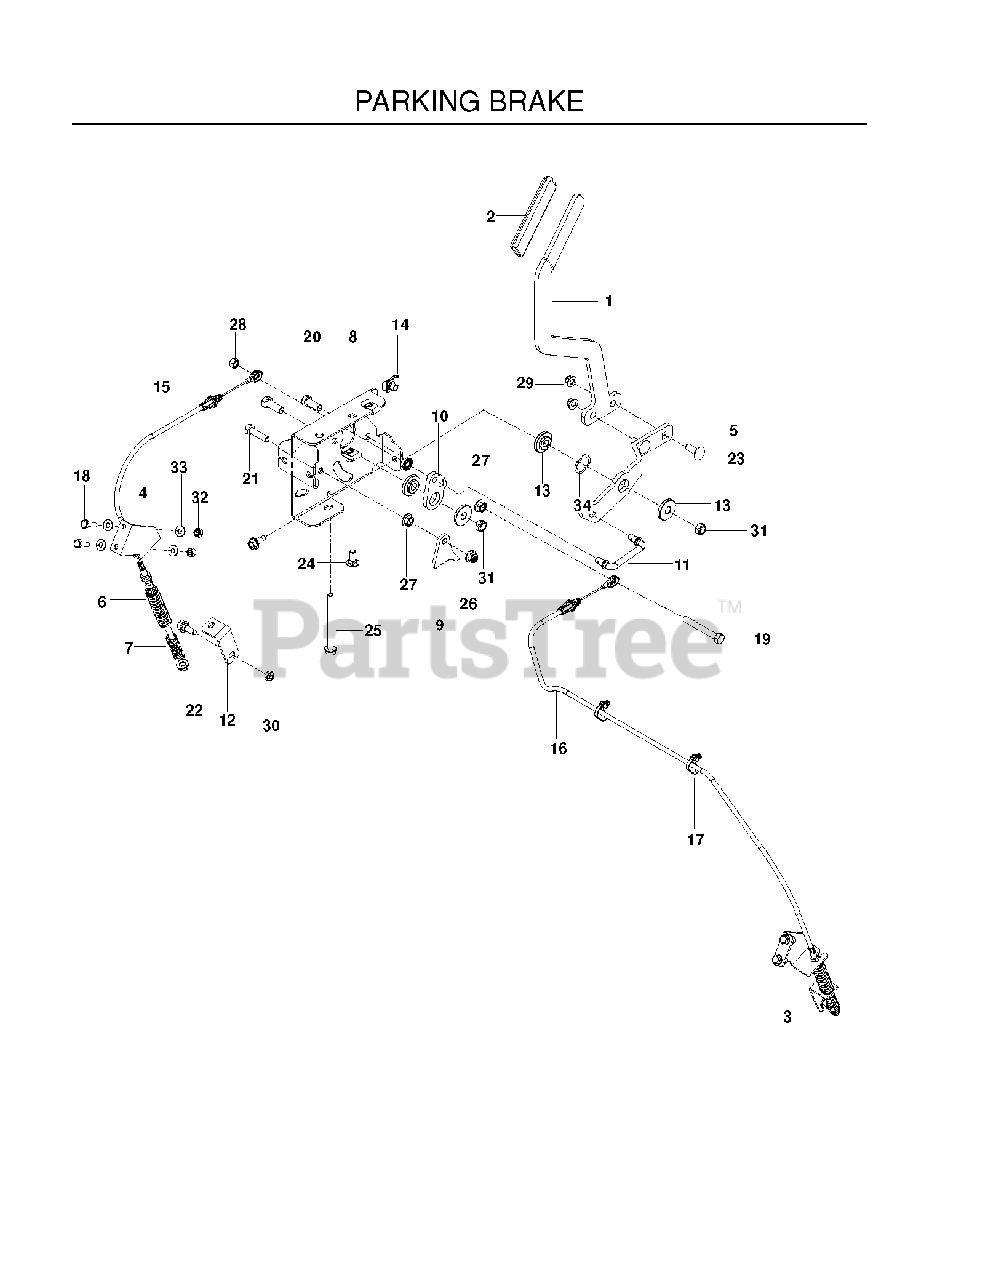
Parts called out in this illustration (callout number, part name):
2	GRIP BRAKE HANDLE
3	BRKT, BRAKE RT, BLK
4	BRKT, BRAKE LT, BLK
5	LEVER, BRAKE
6	SPRING, RETURN
7	SPRING, ENGAGEMENT
8	MOUNT, BRAKE WLDMT
9	ACTUATOR, SWITCH
10	BELLCRANK, BRAKE
11	LINKAGE, BRAKE
12	BRKT, BRAKE, BLK
13	BUSHING, BRAKE
14	U-CLIP 5/16-18 NUT RETAINER
15	CABLE, BRAKE, SHORT
16	CABLE, BRAKE, LONG
17	TIE WRAP, 8-3/8", W/CLIP
18	HCS 1/4-20X7/8 GR5
19	HCS 5/16-18 X 2 1/2 TPBLT
20	HCS 3/8C X 1
21	HCS 5/16C X 1
22	BOLT, SHOULDER
23	RHSNB 3/8C X 1
24	BOLT 5/16C X 3/4" CARRIAGE
25	HHFS 5/16-18 X 3 3/4
26	5/16-18 NYLOC FLANGE NUT
27	NUT 5/16C WHIZ
28	NUT 5/16 NYLOC
29	NUT 3/8-16 HEX FLG NYLOC ZD
30	5/16-18 THIN PROF NY
31	NUT HEX 3/8-16 NYLON, THIN
32	NUT 1/4-20 NYLOC
33	WASHER 1/4 SAE
34	WASHER, .825 X 1.087, WAVE
